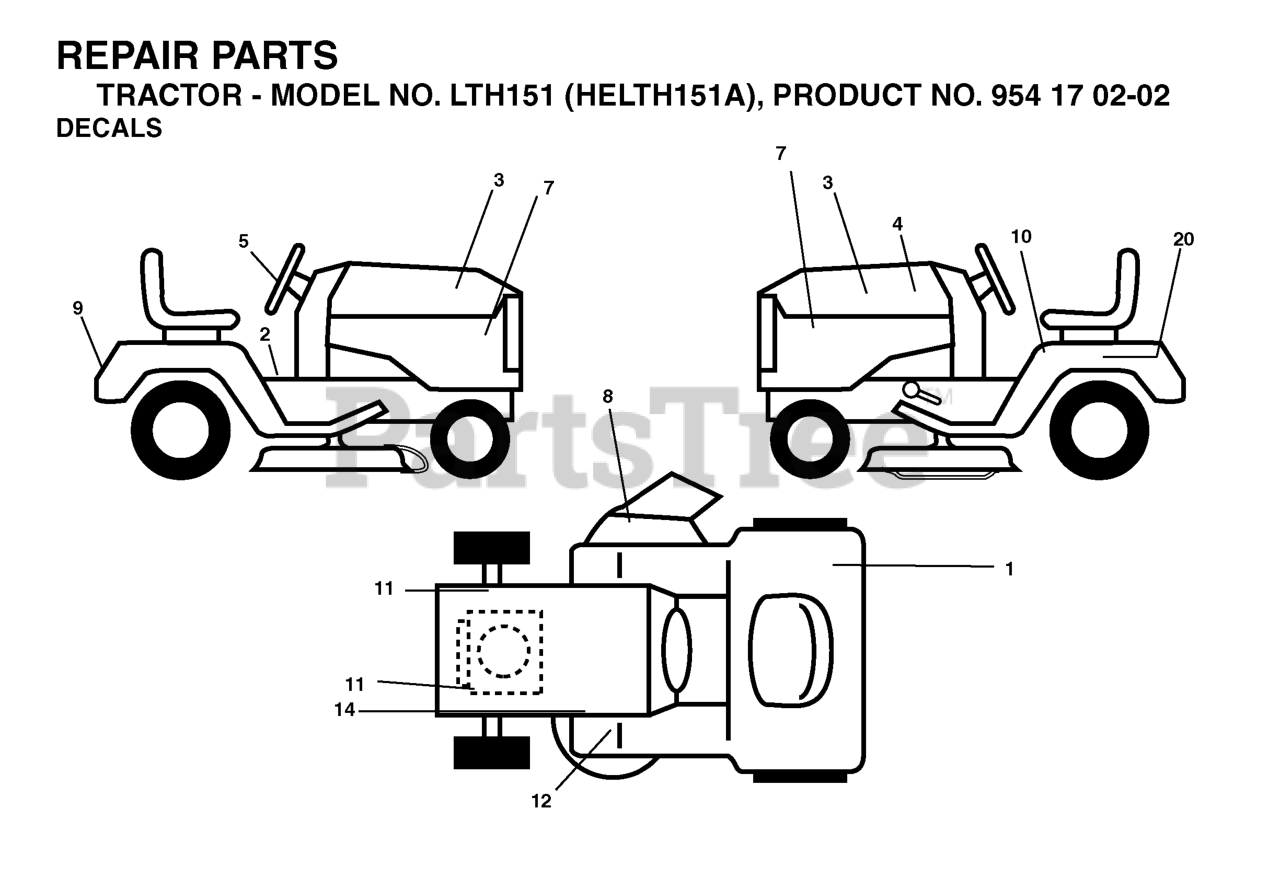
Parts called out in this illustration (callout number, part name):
1	Decal, Fender 100 DB/CE
2	DECAL PARK BRAKE
5	DECAL.STEERING.HUSQ.BLUE
7	DECAL.HOOD.HUSQVARNA.INTERNATI
8	DECAL.INTERNATIONL.CUTFINGER
10	DECAL READ OWNER'S MAN SYMS
12	DECAL
14	DECAL V-BELT SCHEMATIC
20	DECAL BTRY SYMBOLS
